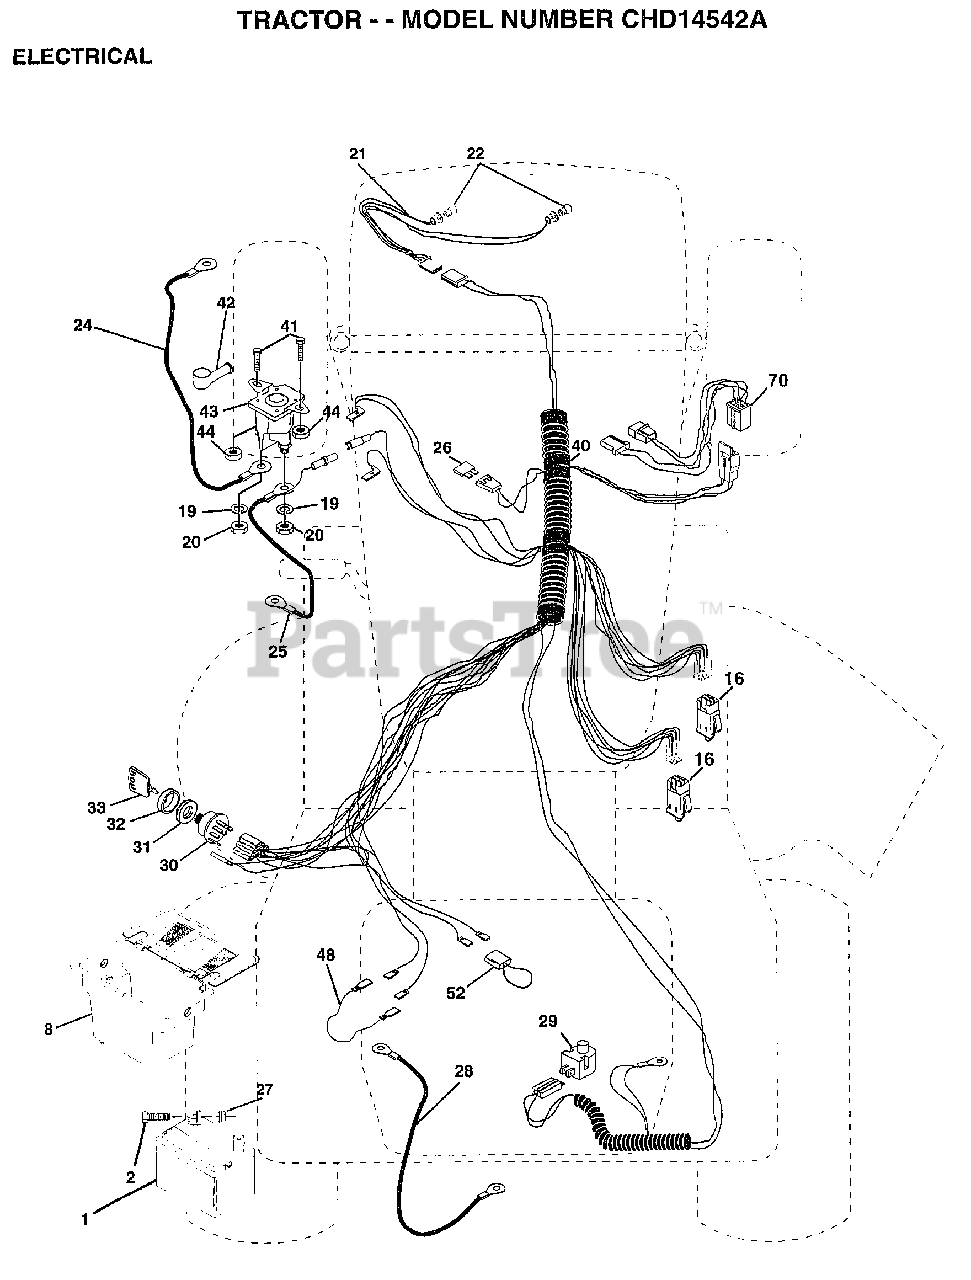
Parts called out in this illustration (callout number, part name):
2	BOLT LT
8	"CASE,BATTERY.MECH"
16	SWITCH INTERLOCK
20	NUT
21	HARNESS.ASM.LIGHT W/4152J
22	HEADLAMP BULB
24	"CABLE T, BATTERY"
25	CABLE.BTRY.6GA.RD
26	FUSE.15 AMP
27	NUT
28	CABLE T
29	SWITCH SEAT
30	SWITCH IGN 4POS
31	NUT IGNITION
32	COVER KEY SWITCH
33	KEY
40	HARNESS.IGNITION
41	BOLT HXHD FIN
44	NUT HXKEP 1/4X20
48	ADAPTER AMMETER
52	PROTECTION LOOP
70	HARNESS.ENGINE.B&S
